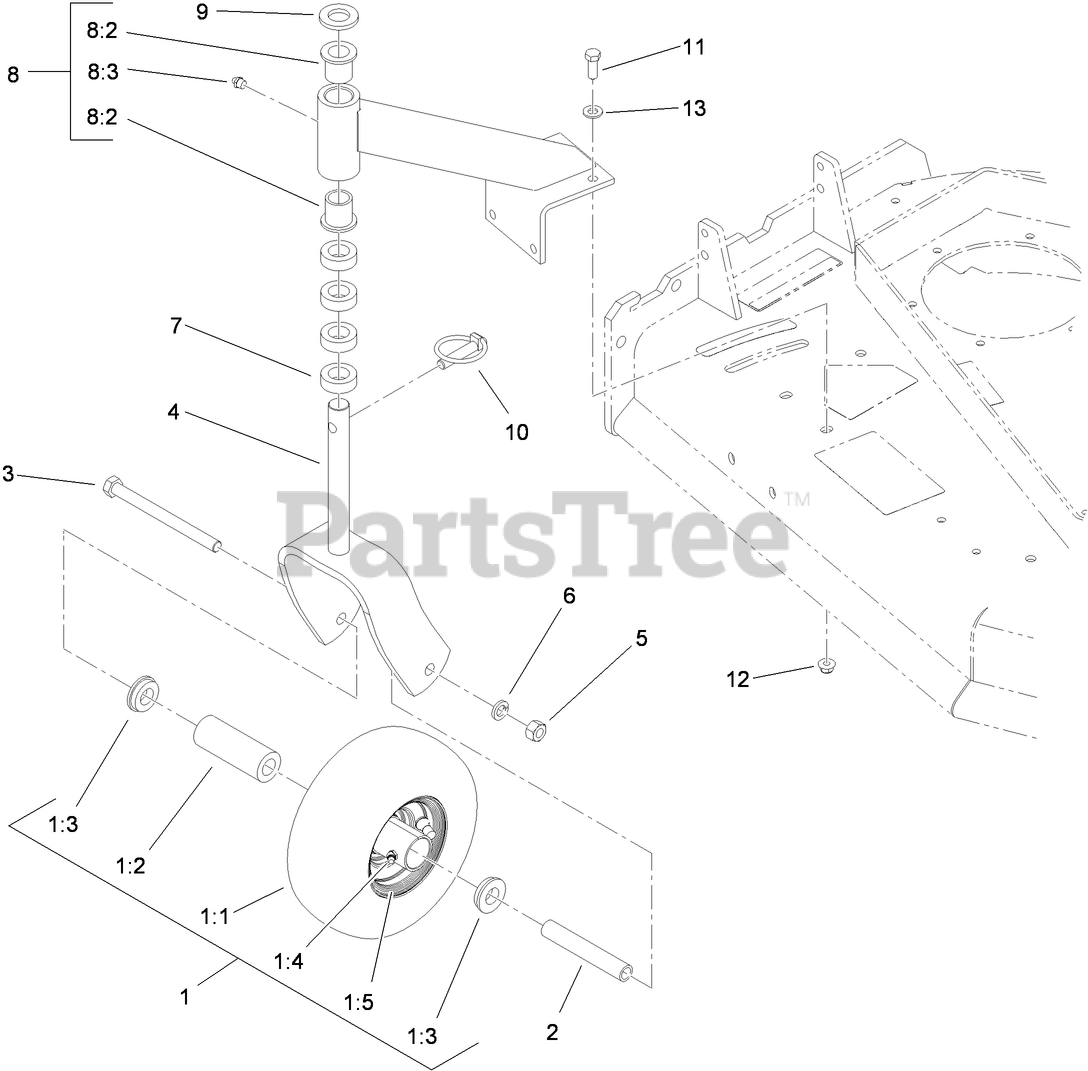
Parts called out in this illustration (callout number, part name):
1	WHEEL AND TIRE ASM
1:1	TIRE
1:2	BEARING
1:3	BUSHING
1:4	FITTING-GREASE
1:5	WHEEL
2	SPACER
3	SCREW-HH
4	FORK
5	NUT-HH
6	WASHER-LOCK
7	SPACER-CASTER
8	SUPPORT ASM
8:2	BEARING-FLANGED
8:3	FITTING-GREASE
9	WASHER-FLAT
11	SCREW-HH
12	NUT-HF, NI
13	WASHER-FLAT
